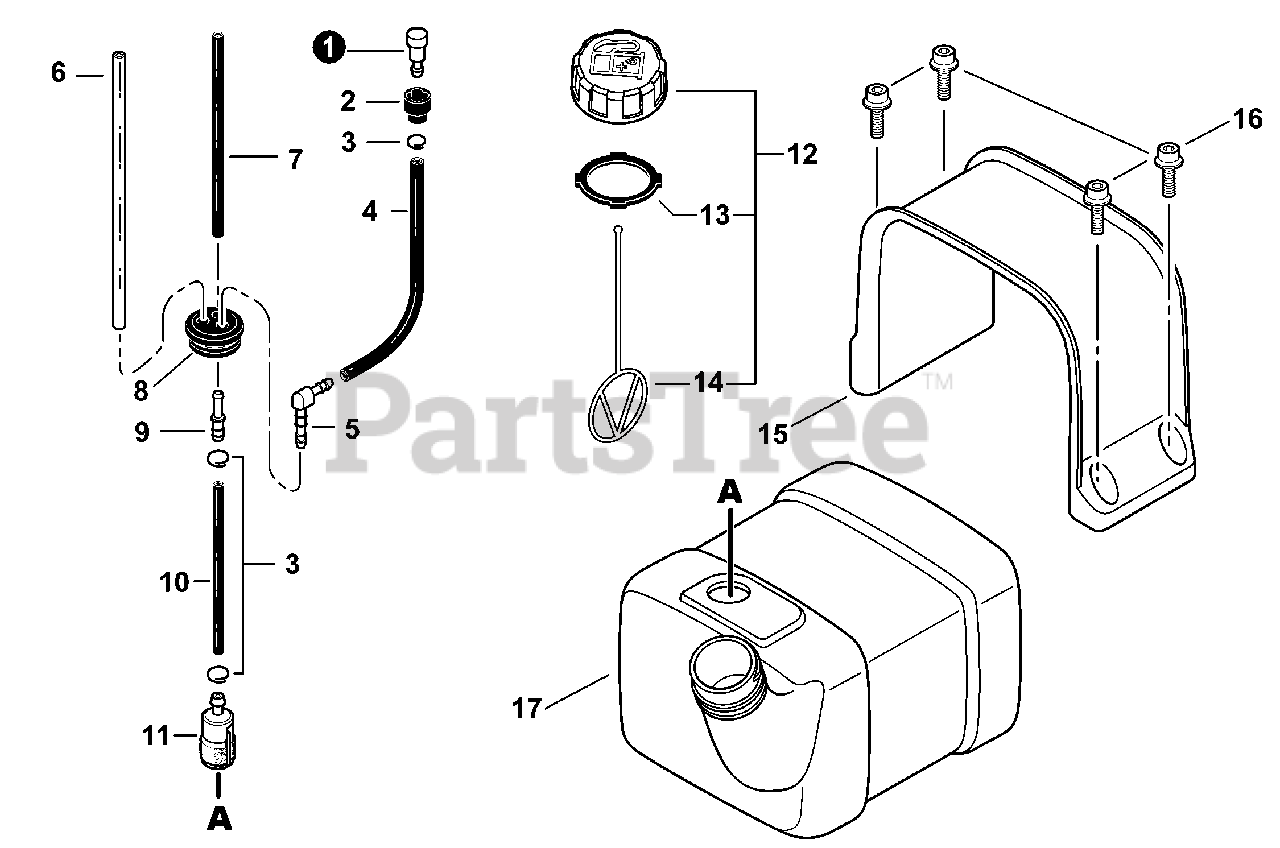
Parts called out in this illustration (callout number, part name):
1	VENT ASSY
2	HOLDER, VENT
3	CLIP Ø6.5 MM
4	PIPE, VENT 3×6×145 MM
5	CONNECTOR, PIPE
6	PIPE, FUEL RETURN 3×6×145
7	PIPE, FUEL 3×5×110
8	GROMMET, FUEL
9	CONNECTOR, PIPE Ø5ר3.5
10	PIPE, FUEL 3×6×120 BLACK
11	FILTER, FUEL
12	CAP ASSY, FUEL
13	GASKET, FUEL CAP
14	CONNECTOR, CAP L= 100 MM
15	BRACKET, FUEL TANK
16	BOLT 5×16
17	TANK, FUEL
